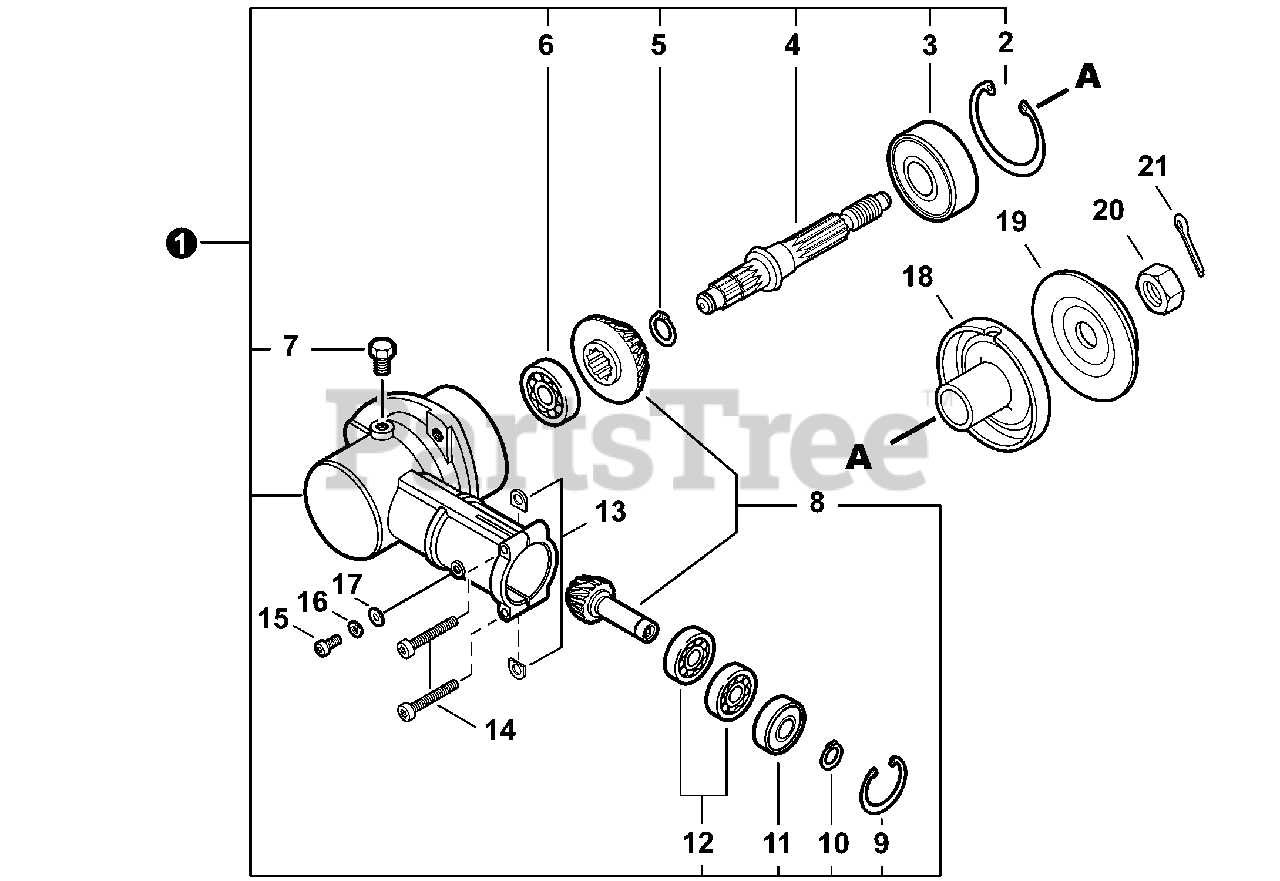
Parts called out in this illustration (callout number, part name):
1	GEAR CASE ASSY
2	RING, SNAP 42
3	BEARING, BALL 6302
4	SHAFT, GEAR
5	RING, SNAP 12
6	BEARING, BALL 629
7	BOLT M8×1.25
8	GEAR SET
9	RING, SNAP 22
10	RING, SNAP 10
11	BEARING, BALL 6900-Z
12	BEARING, BALL 6900
13	D-WASHER
14	BOLT, TORX 5×25
15	BOLT, TORX 5×12
16	WASHER, SPRING 5
17	WASHER, FLAT 5.5×10×0.8
18	PLATE, ADAPTOR - UPPER
19	PLATE, ADAPTOR - LOWER
20	NUT 10×1.25 LH
21	PIN, COTTER 2×22
